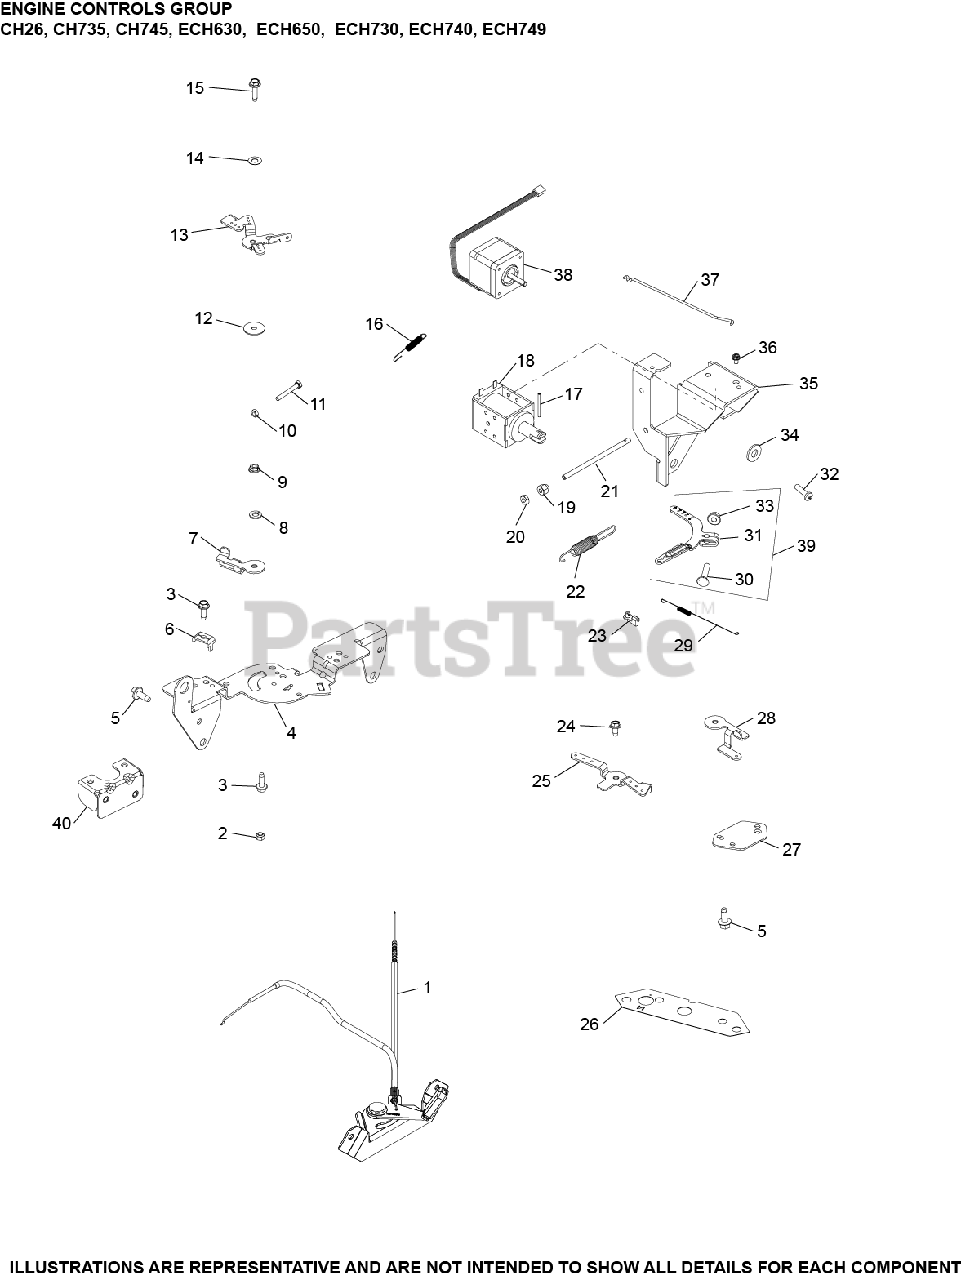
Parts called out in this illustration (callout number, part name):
1	CABLE, CONTROL ASSEMBLY USE 24 225 13-S
2	NUT, LOCK M5X.8
3	SCREW,FLG THD FRM M5X0.8X16-(#25086398S)
4	BRACKET, CONTROL
5	SCREW,FLG THD FRM M6X1.0X16-(#25086397S)
6	CLAMP, CABLE
7	LEVER,THROTTLE ACTUATOR-USE(24 090 65-S
8	WASHER, SPRING LOCK 1/4"
9	NUT, FLG M5X.8
10	NUT, M4X0.7
11	SCREW, CAP M4X.7X30
12	WASHER, FLAT 5.5 MM
14	WASHER, SPRING 1/4"
15	SCREW, FLG THD FRM M5X.8X20-(#25086399S)
16	SPRING, THROTTLE LIMITER
22	SPRING, GOVERNOR (BLACK)
23	BUSHING, THROTTLE LINKAGE
24	SCREW, FLG THD FRM M5X.8X10
25	LEVER, THROTTLE CONTROL
26	LABEL, CONTROL PANEL
27	BRACKET, CABLE SUPPORT
29	SPRING, LINKAGE
30	BOLT, RD HD SQ NECK M6X1.0X25
31	LEVER, GOVERNOR-USE 24 090 57-S
32	SCREW, PHL HD 11-16X3/4"
33	NUT, FLG M6X1.0
37	LINKAGE, THROTTLE
